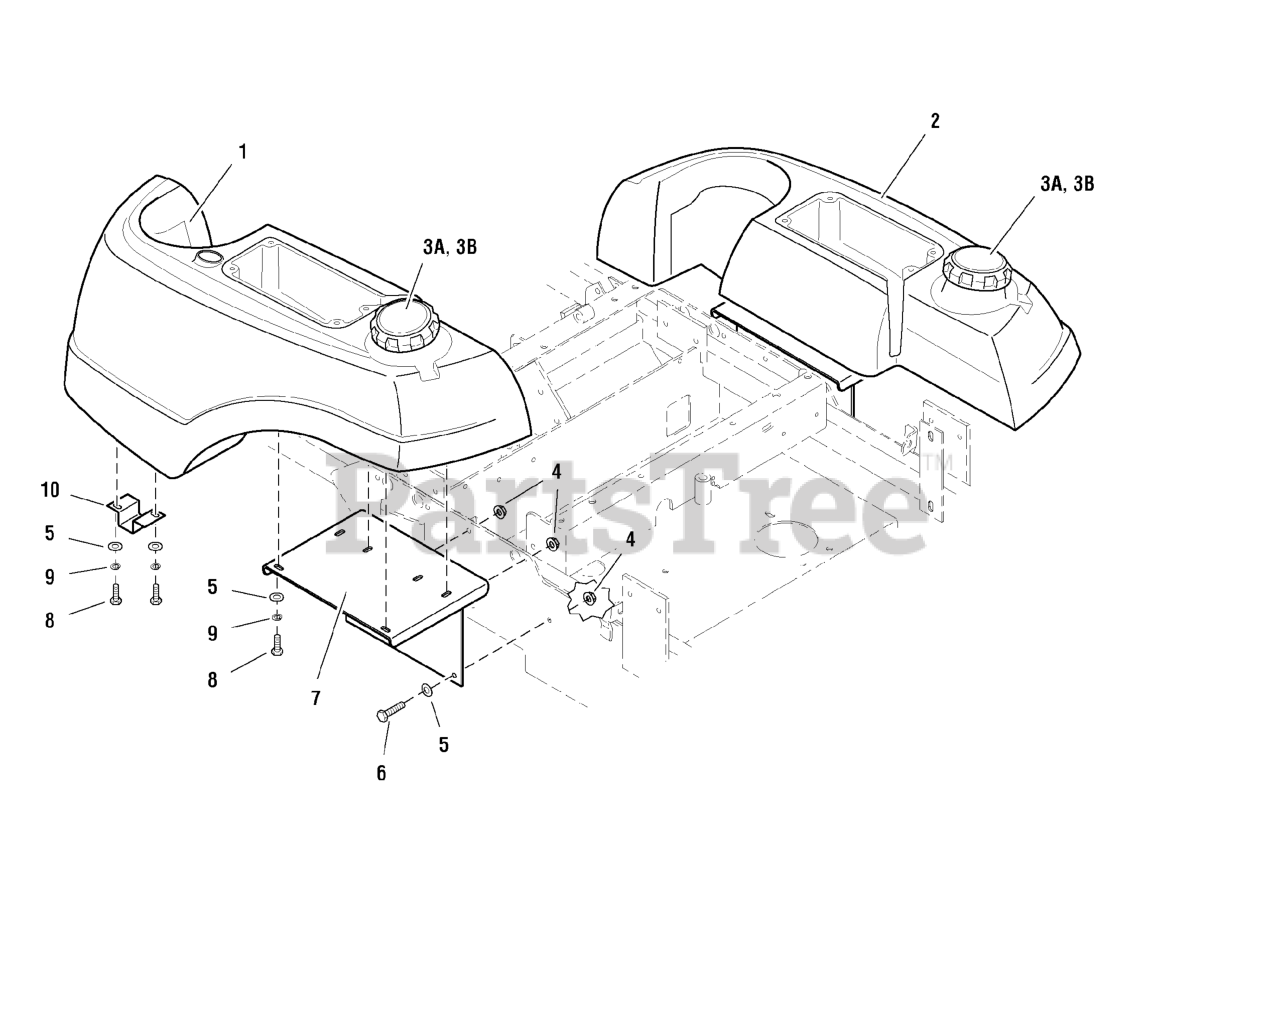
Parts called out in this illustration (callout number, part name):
1	FUEL TANK, IS5000Z, LH
2	FUEL TANK, IS5000Z, RH
3A	FUEL TANK CAP, DIESEL
3B	CAP, FUEL TANK, 3-1/2 NECK
4	NUT, 5/16-18 HEX SERRATED FLANGE (LARGE)
5	WASHER, 5/16" SAE
6	BOLT, 5/16-18 X 1 GD5 YZ
7	FUEL TANK MOUNT
8	BOLT, 5/16-18 X 3/4 GD5
9	WASHER, 5/16 LOCK CZ
10	GUARD, Tank Valve
